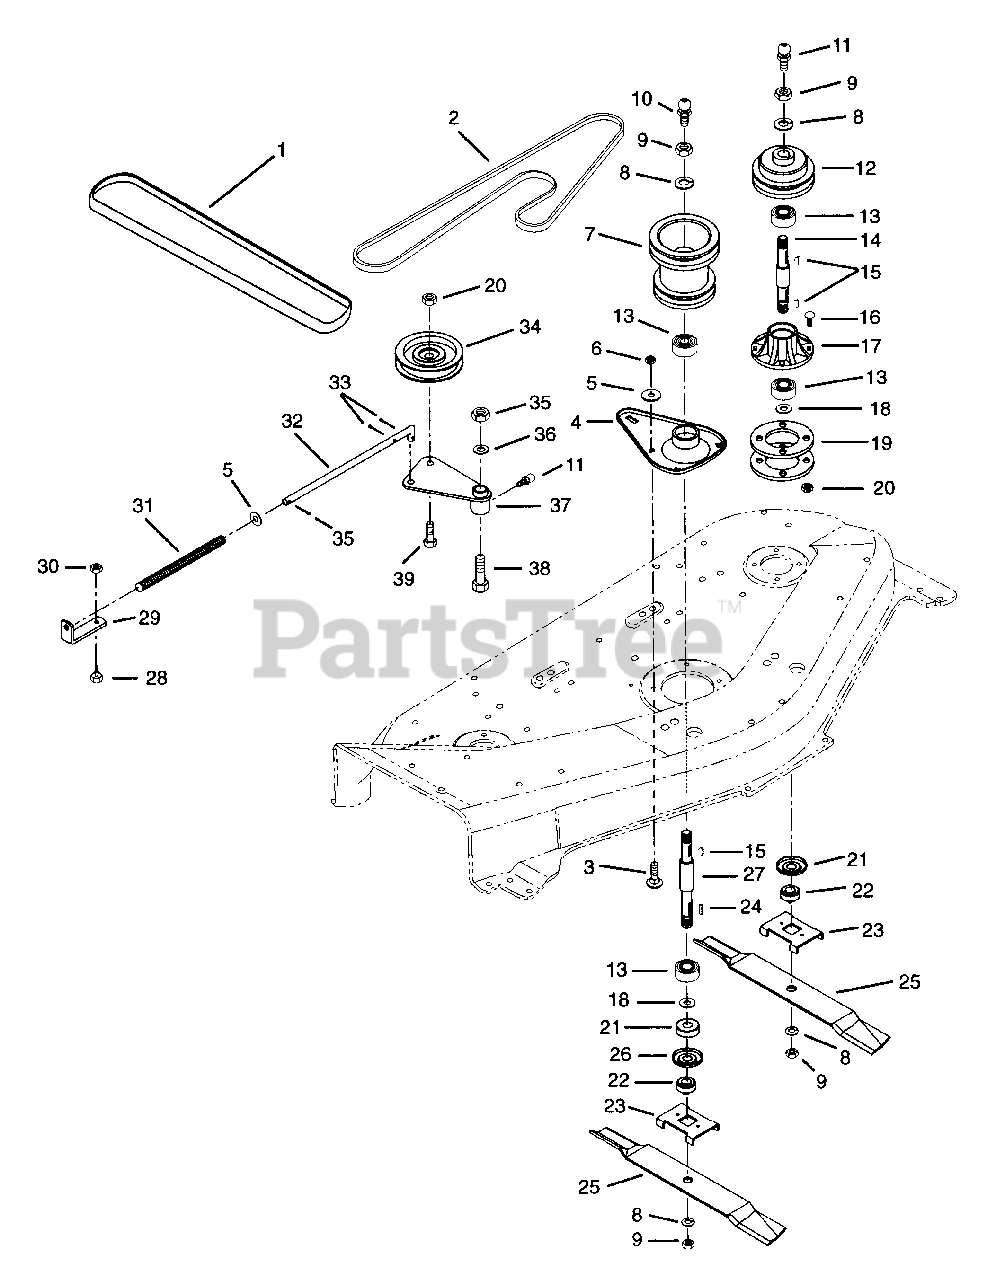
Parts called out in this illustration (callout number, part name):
1	V-BELT, 4L-RAW EDGE
2	V-BELT, HA-WRAPPED
3	BLT-RDHDSQNK .38-16X.62 GR5 PL
4	HOUSING,SPINDLE
5	WSHR-FL-STL.406X.812X.065PL
6	NUT-LK-CTR .375-16 GR A PL
8	WSHR-LK .750X.188 MED PL
9	NUT-JAM .75-10 PL
10	GREASE ZERK
11	SPIN DRIVE ZERK FITTING
13	BRG-BALL .750X1.781X.61
14	SPINDLE SHAFT W/ZERK
15	KEY-WDRF .188X.625X.25 SAE 61
16	BLT-RDHDSQNK .375-16X.75 PL
17	SPINDLE HOUSING
18	WSHR-FL-STL .754X1.000X.032
19	SPACER, SPINDLE
20	NUT-LK-JAM-CTR .375-16 PL
21	BEARING SLINGER
22	RETAINER HUB
23	BLADE TRAY
24	KEY-SQ .188X.625X.188 SAE 61
25	BLADE
26	WSHR-FL-STL .755X1.250X.125
27	SPINDLE SHAFT W/ZERK & KEY
28	BLT-HEX .31-18X.50 GR5
29	BRACKET
30	NUT-LK .312-18 GR A PL
31	SG-COMP .106X.63X 12.0 WLD 62
32	ROD-IDLER SPRING
33	PIN-COTR .09X.75 PL
34	IDLER-FLAT 4.00 X .38 NWHAMSHR
35	NUT-LK-CTR .50-13
36	WSHR-FL-STL .505X.880X.072 PL
37	IDLER ARM W/ZERK
38	BLT-HEX .50-13X1.50 PL GR2
39	BLT-BTHD .38-16X1.25 GR5
